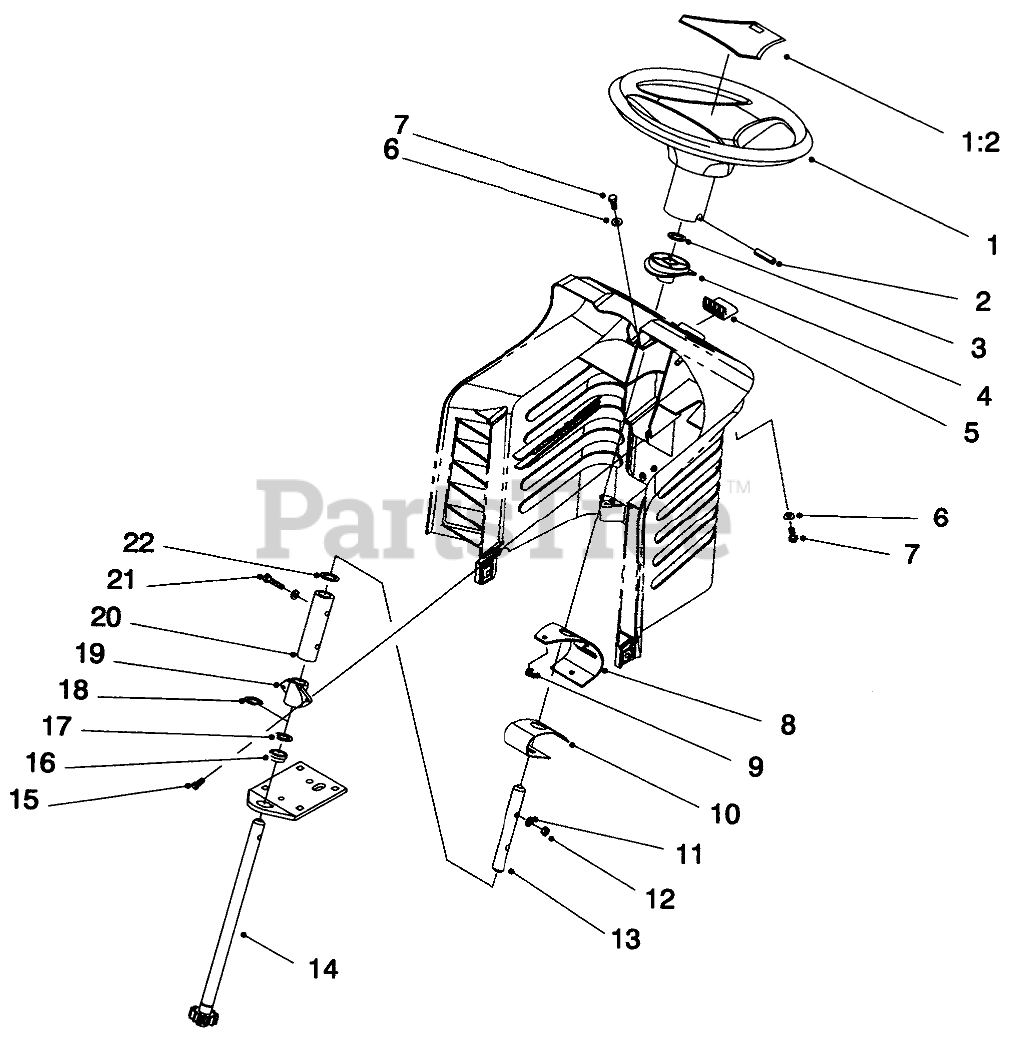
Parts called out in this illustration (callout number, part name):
1	Wheel-Steering (Incl. Ref. #1:2)
1:2	COVER-WHEEL
2	PIN-ROLL
3	PUSH-ON RETAINING RING
4	BUSHING-SLIDING
5	RELEASE BUTTON
6	WASHER-FLAT
7	SCREW-HH
8	BACKUP BRACKET
9	NUT-LOCK, NI
10	SPRING LEAF
11	WASHER
12	NUT-LOCK, NI
13	UPPER STEERING SHAFT
14	SHORT STRG SHAFT WA
15	SCREW-SPECIAL
16	BEARING-FLANGE
17	WASHER-THRUST
18	E-RING
19	BUSHING STATIONARY
20	COUPLING, STEERING
21	SCREW-HH
22	WASHER-THRUST
